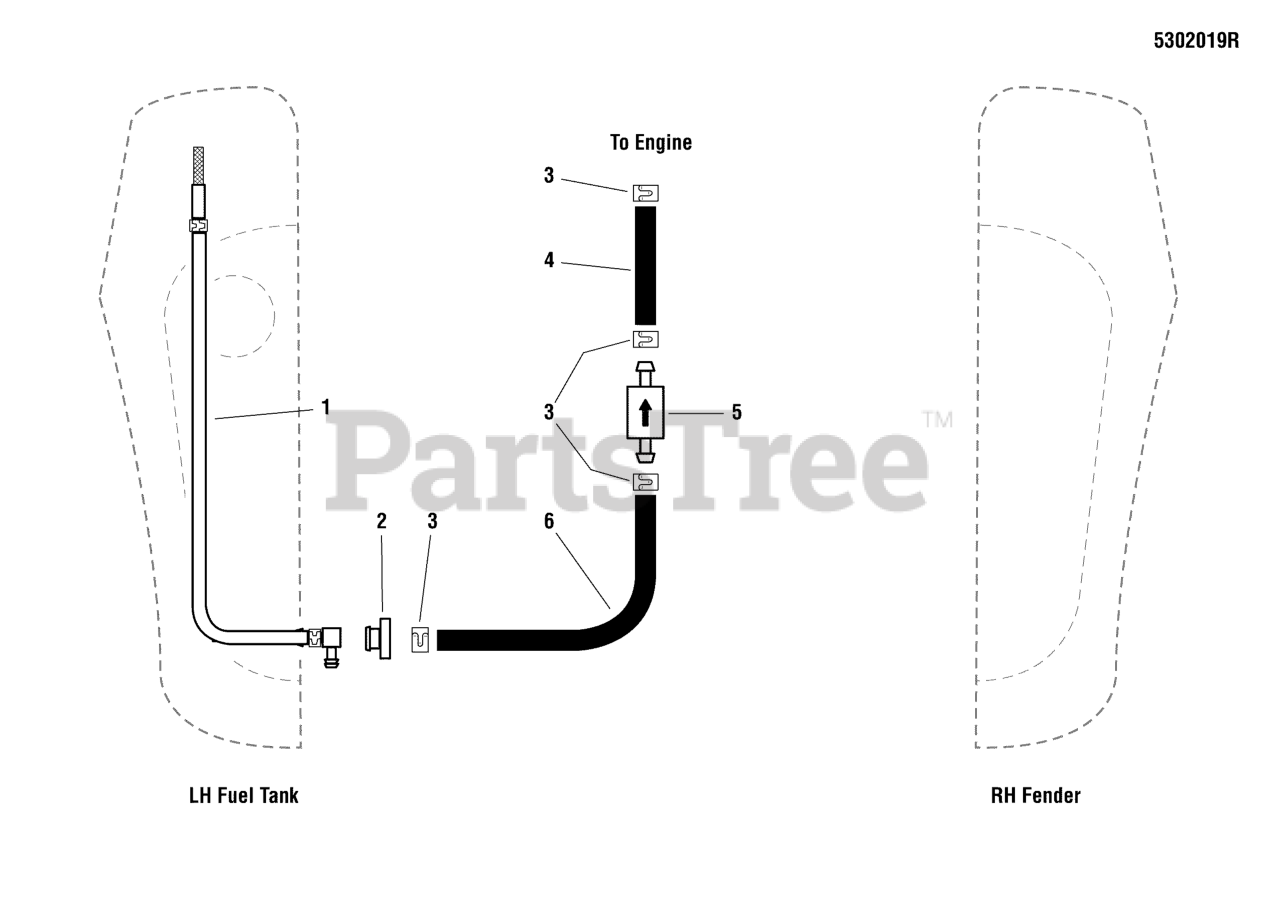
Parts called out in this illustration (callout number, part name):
1	PICKUP TUBE ASM, FUEL TANK, 18.38" (SV)
2	BUSHING-FUEL TANK RED RUBBER
3	CLAMP, HOSE, EXTERNAL, 1/2 - RED
4	HOSE, 1/4 FUEL LINE, 10"
5	FUEL FILTER (SV)
6	HOSE, 1/4" FUEL, 28.00"
